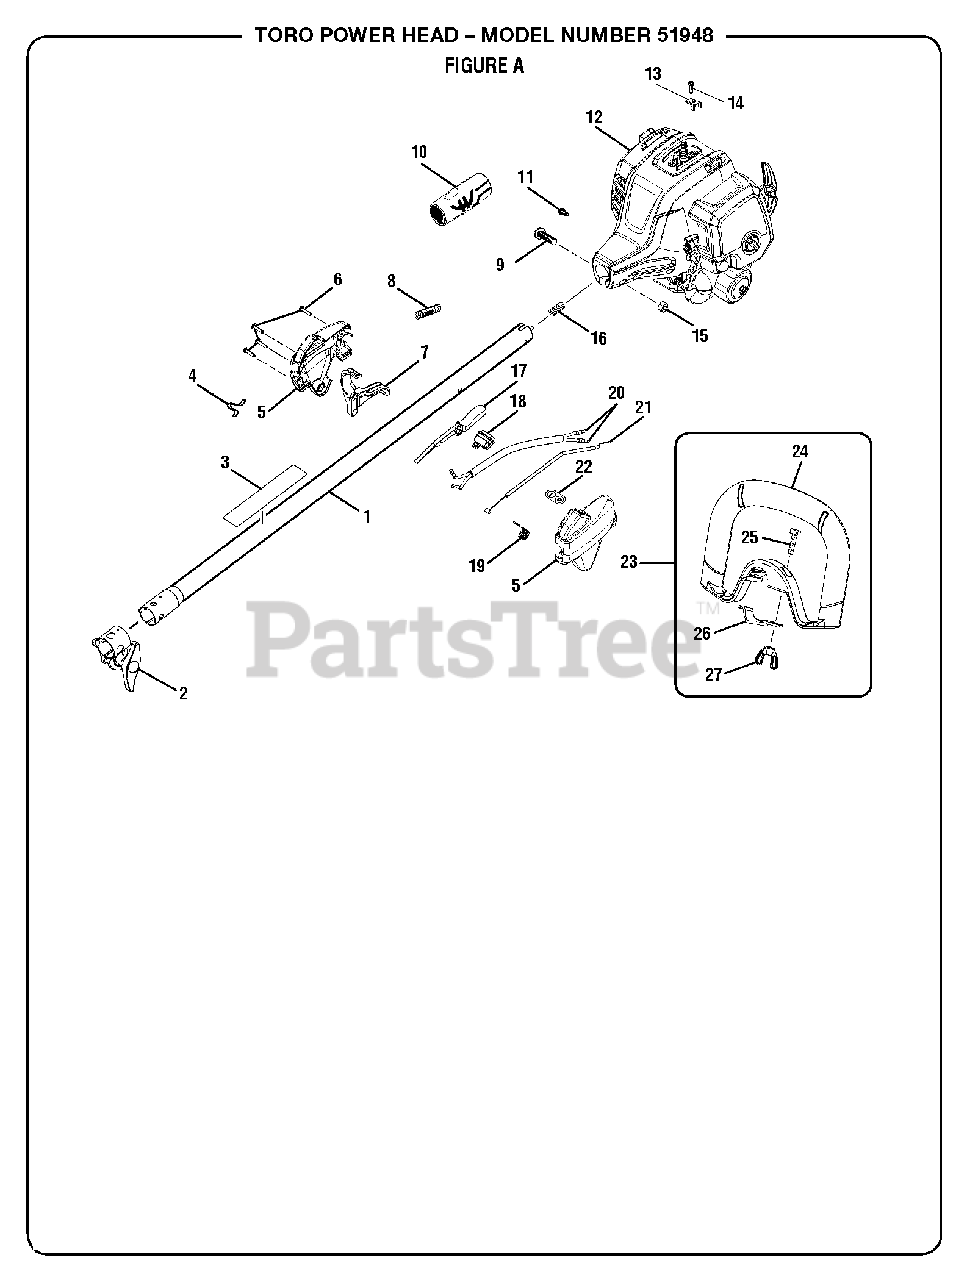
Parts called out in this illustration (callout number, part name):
1	Upper Boom Assembly
2	Boom Clamp Assembly
3	Warning Label
4	Shoulder Strap Clip
5	Control Handle Assembly
6	Screw (M4 x 20 mm, T20 Torx Hd.)
8	Corrugated Tube
9	Screw (M6 x 30 mm)
10	Rear Handle Grip
11	Screw (M4 x 8 mm, T20 Torx Hd.)
12	Powerhead Assembly
13	Throttle Cable Clamp
14	Screw (M4 x 16 mm)
15	Hex Nut (M6.3 x 1)
16	Compression Spring
17	Trigger Lock
18	On/Stop Switch
19	Throttle Cable Spring
20	Lead Assembly
21	Throttle Cable
22	On/Stop Label
23	Front Handle Assembly
24	Front Handle w/Grip
25	Screw (1/4-20 x 1 in., Sq. Hd.)
26	Front Handle Clamp
27	Wing Nut (1/4-20)
